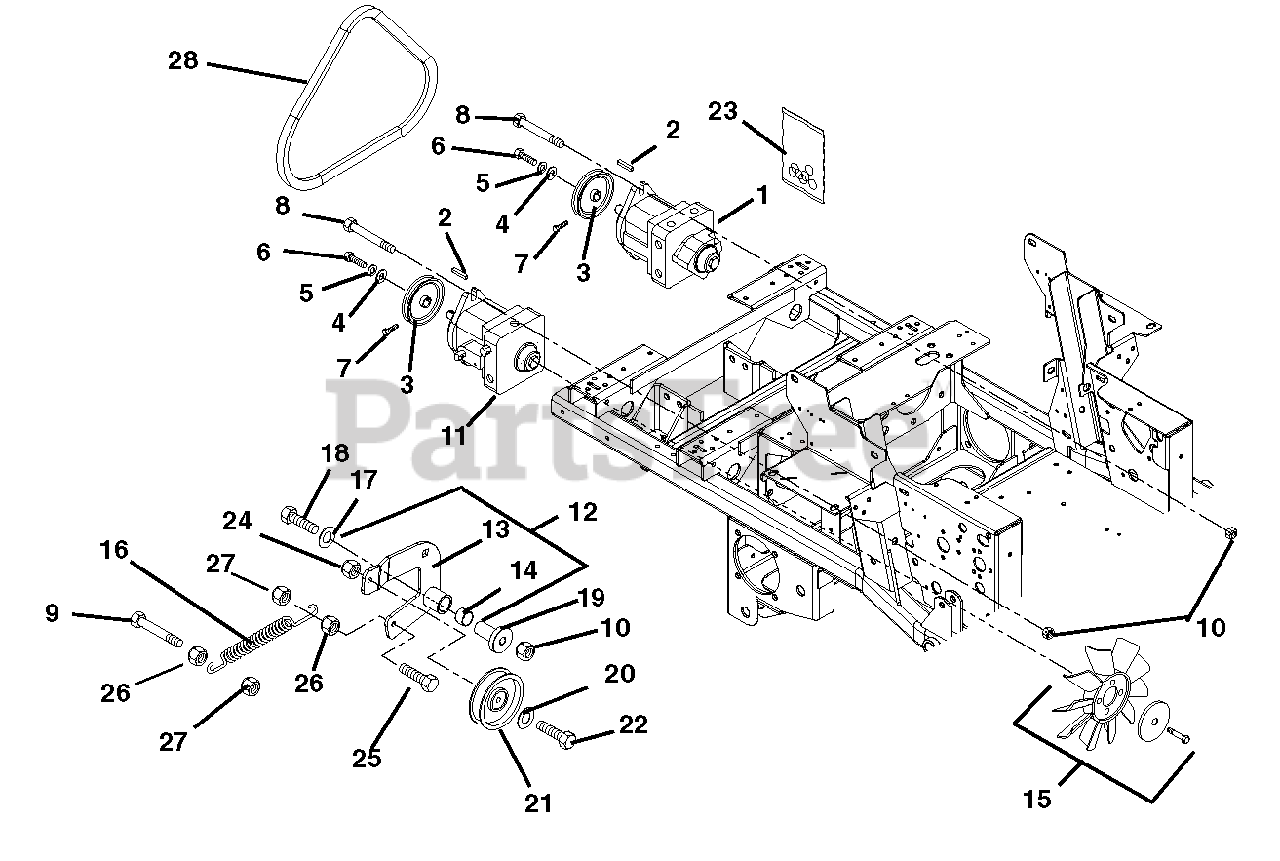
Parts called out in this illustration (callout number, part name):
1	Pump, Hydraulic with Auxiliary
2	Key, Square 5 x 5 x 30mm Plain
3	Sheave, Poly V .671 x 4.125
4	Washer, Flat Steel .281 x 1.000 x .063
5	Washer, Locking .25 x .062
6	Bolt, Hex M6 x 1.0 x 16
7	Screw, Socket Head .25-20 x .50 YZ EP80
8	Bolt, Hex .50-13 x 1.50 Grade 5
9	Bolt, Hex .31-18 x 2.50 Grade 5
10	Nut, Locking Top Flange .50-13
11	Pump, Hydraulic (RTN)
12	Assembly, Idler Arm Guard Drive (Includes 13 & 14)
13	Weldment, Idler Arm Ground Drive
14	Bushing, 1.00 x 1.125 x 1.936
15	Fan, Hydro Pump Cooling
16	Spring, Tension
17	Washer, Flat Steel .39 x.75 x.125
18	Bolt, Hex .50-13 x 3.50 Grade 5
19	Bearing, Pedestal
20	Washer, Flat Steel .406 x .812 x .065
21	Assembly, Idler 4"
22	Bolt, Hex .38-16 x 2.0 Grade 5
23	Kit, Pump Seal (BDP-21A)(One kit required for each pump)
24	Nut, Locking Top Flange .38-16
25	Bolt, Hex .31-18 x 1.25 Grade 5
26	Nut, Hex .31-18
27	Nut, Locking Top Flange .31-18
28	Belt, Poly-V 49.50, Hydrostatic 200Z Series
